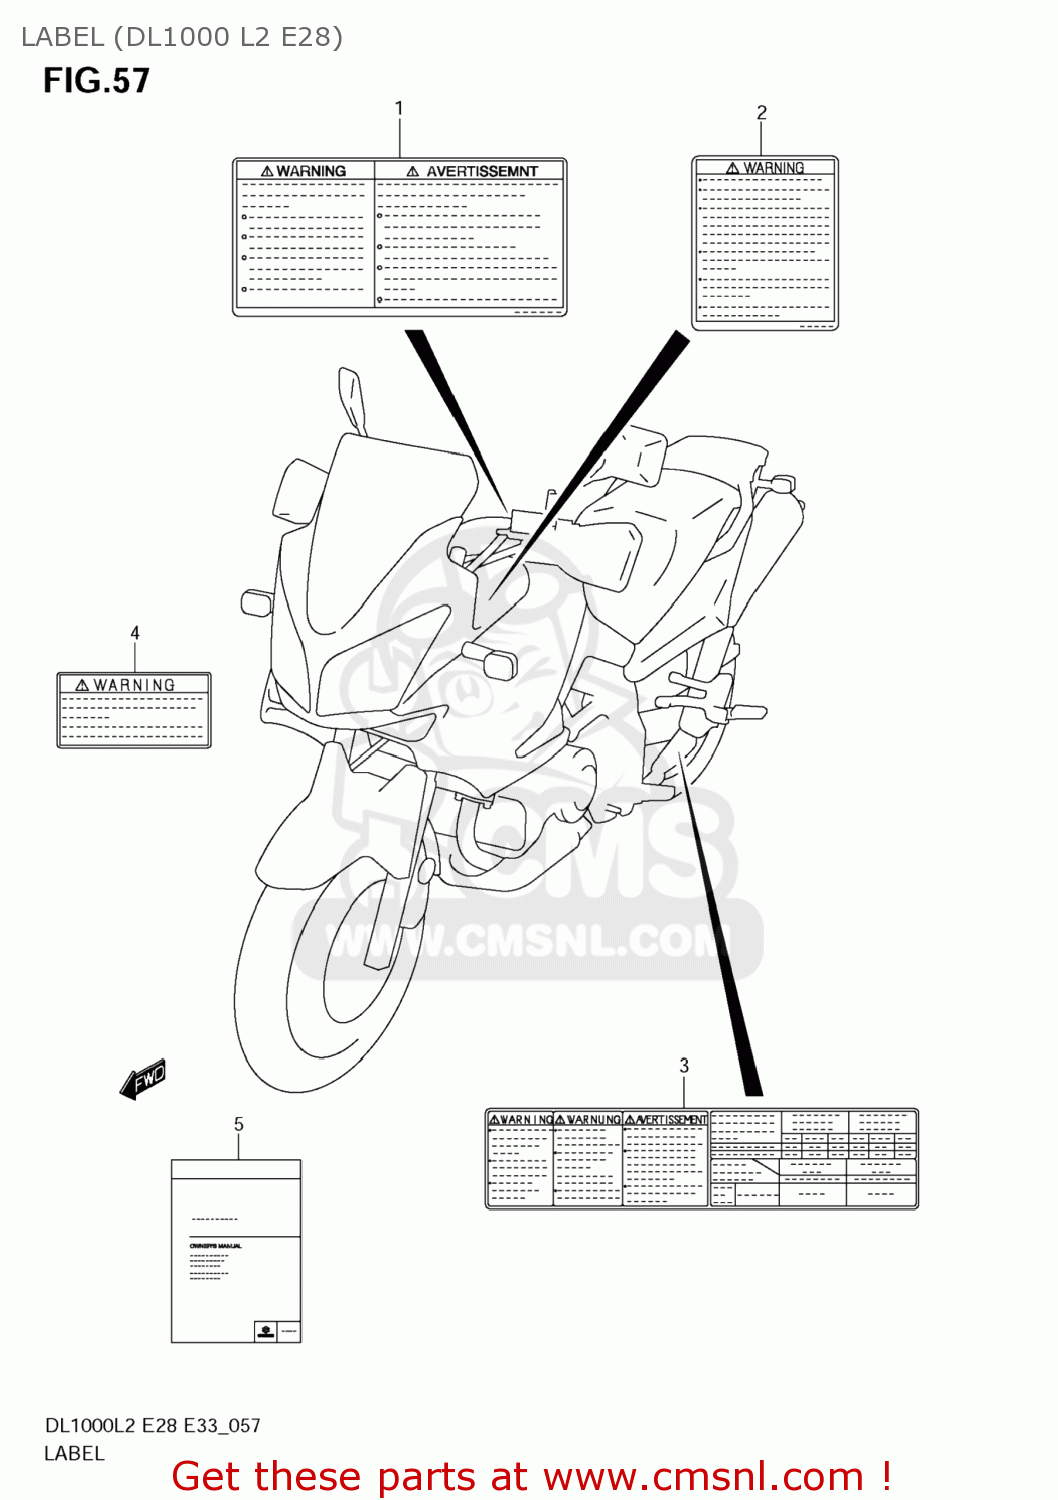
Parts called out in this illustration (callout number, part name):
1	LABEL,GENERAL WARNING
2	LABEL,SCREEN
3	LABEL,TIRE INFORMATION
4	LABEL,WARNING STEERING
5	MANUAL,OWNER'S
